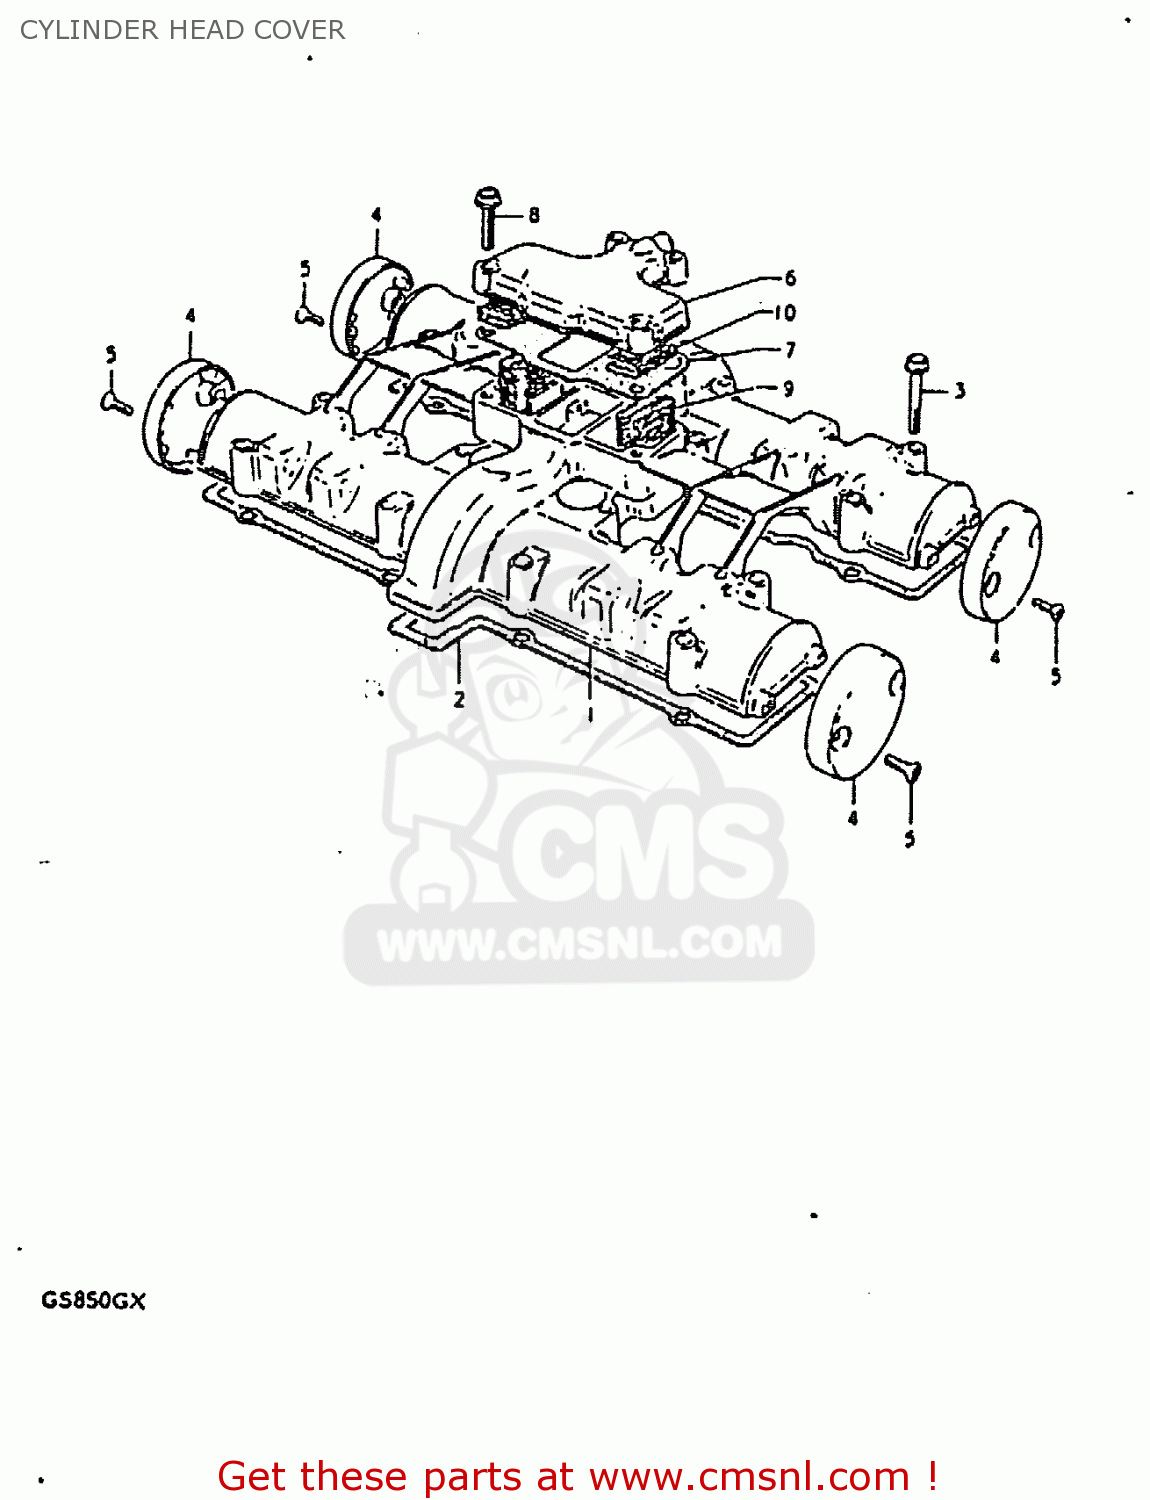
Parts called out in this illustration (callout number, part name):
1	COVER,CYLINDER HEAD
2	GASKET,CYLINDER HEAD COVER (MCA)
3	BOLT
4	CAP,CYLINDER HEAD COVER
5	SCREW 5X12
6	COVER,BREATHER
7	GASKET (MCA)
8	BOLT
9	COVER,BREATHER
10	SEPARATOR,OIL BREATHER
